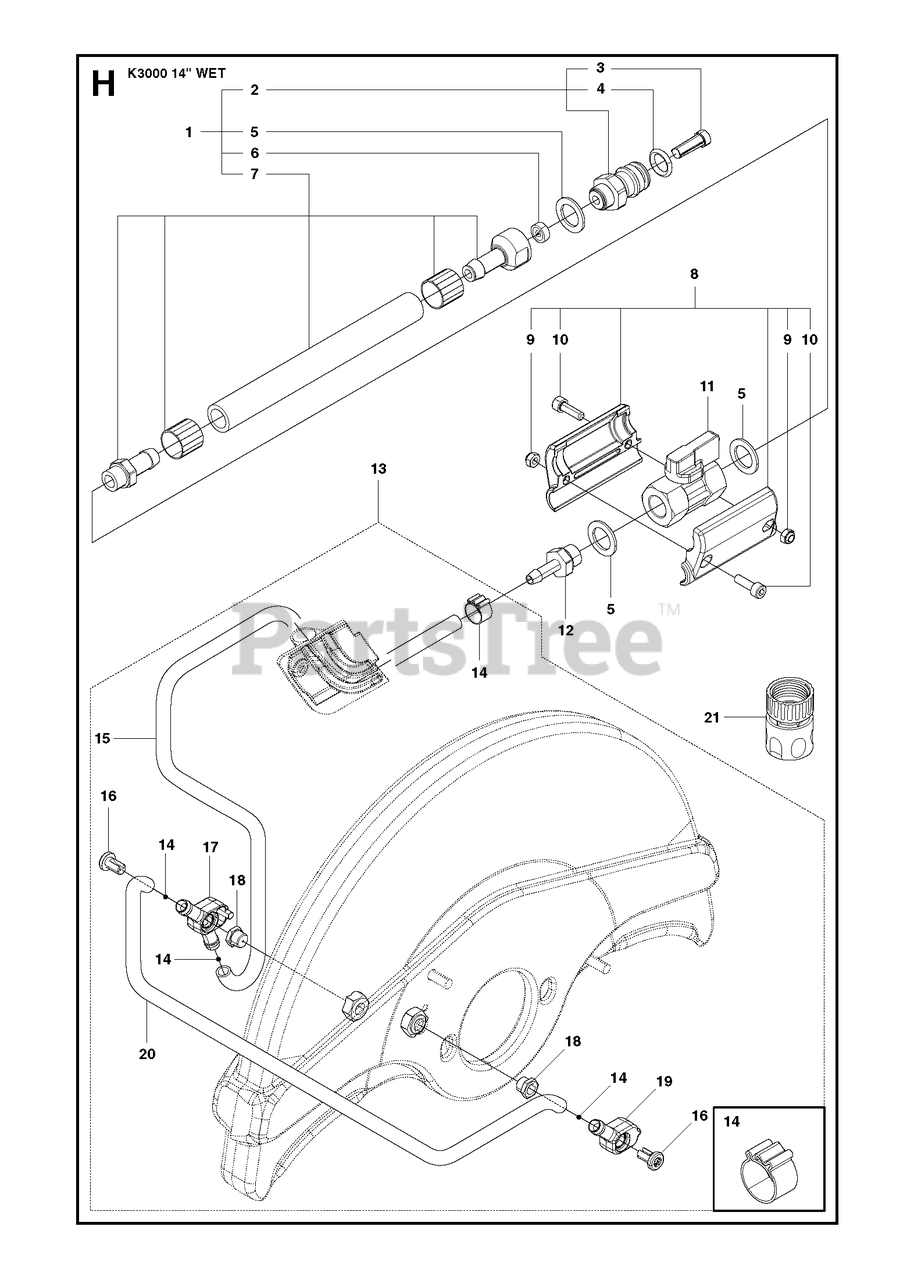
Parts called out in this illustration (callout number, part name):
1	HOSE ASSYIncl. 2, 5 - 7
2	NIPPLEIncl. 3, 4
7	HOSE KIT
13	HOSE KITIncl. 14 - 20
15	HOSE720 mm
16	SCREW ITXSCM
